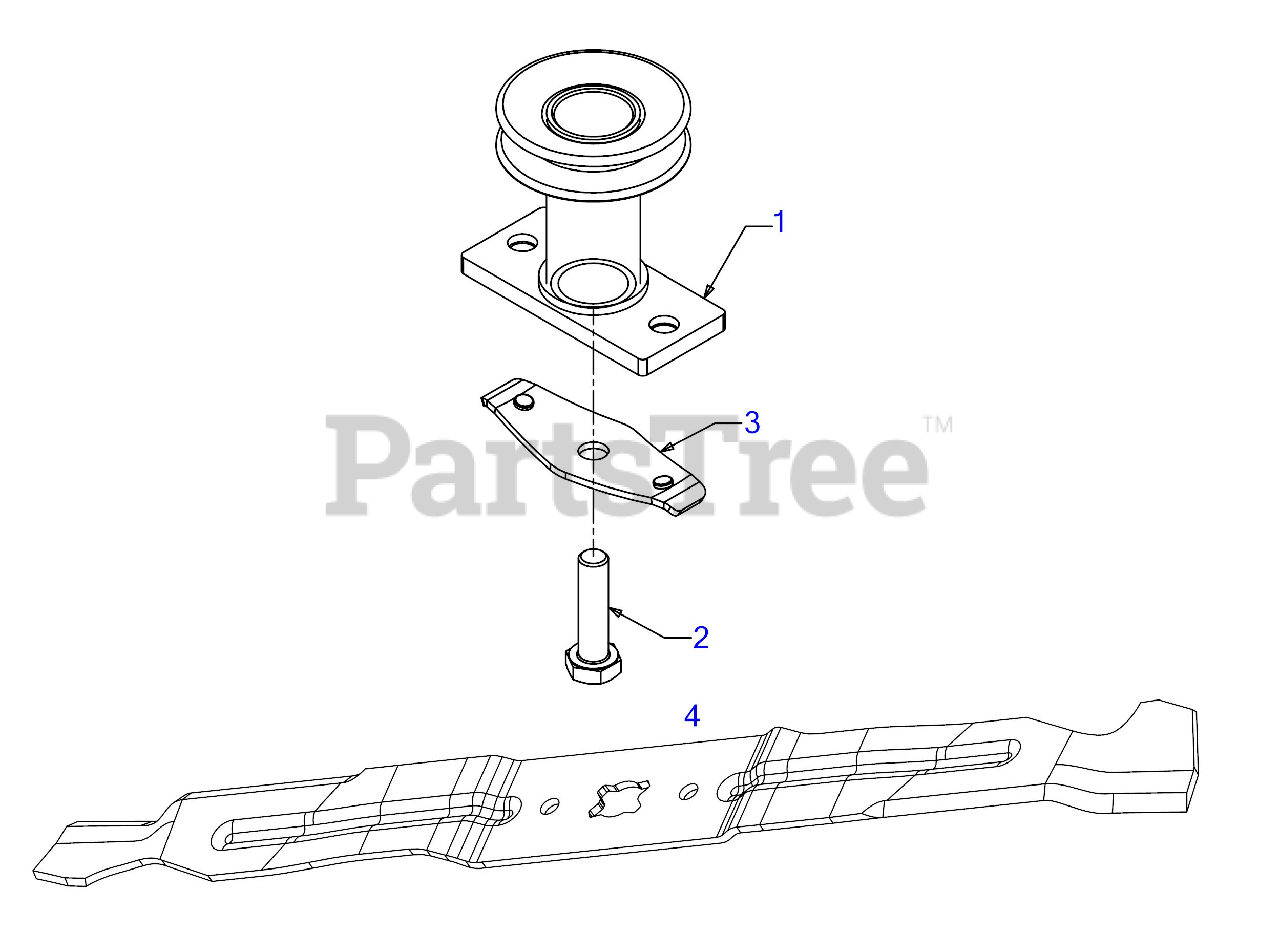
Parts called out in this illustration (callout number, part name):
1	BLADE ADAPTER
2	SCREW 3/8-24 x 1.50 GR8
3	BLADE BELL SUPPORT
4	21" MULCHING BLADE
